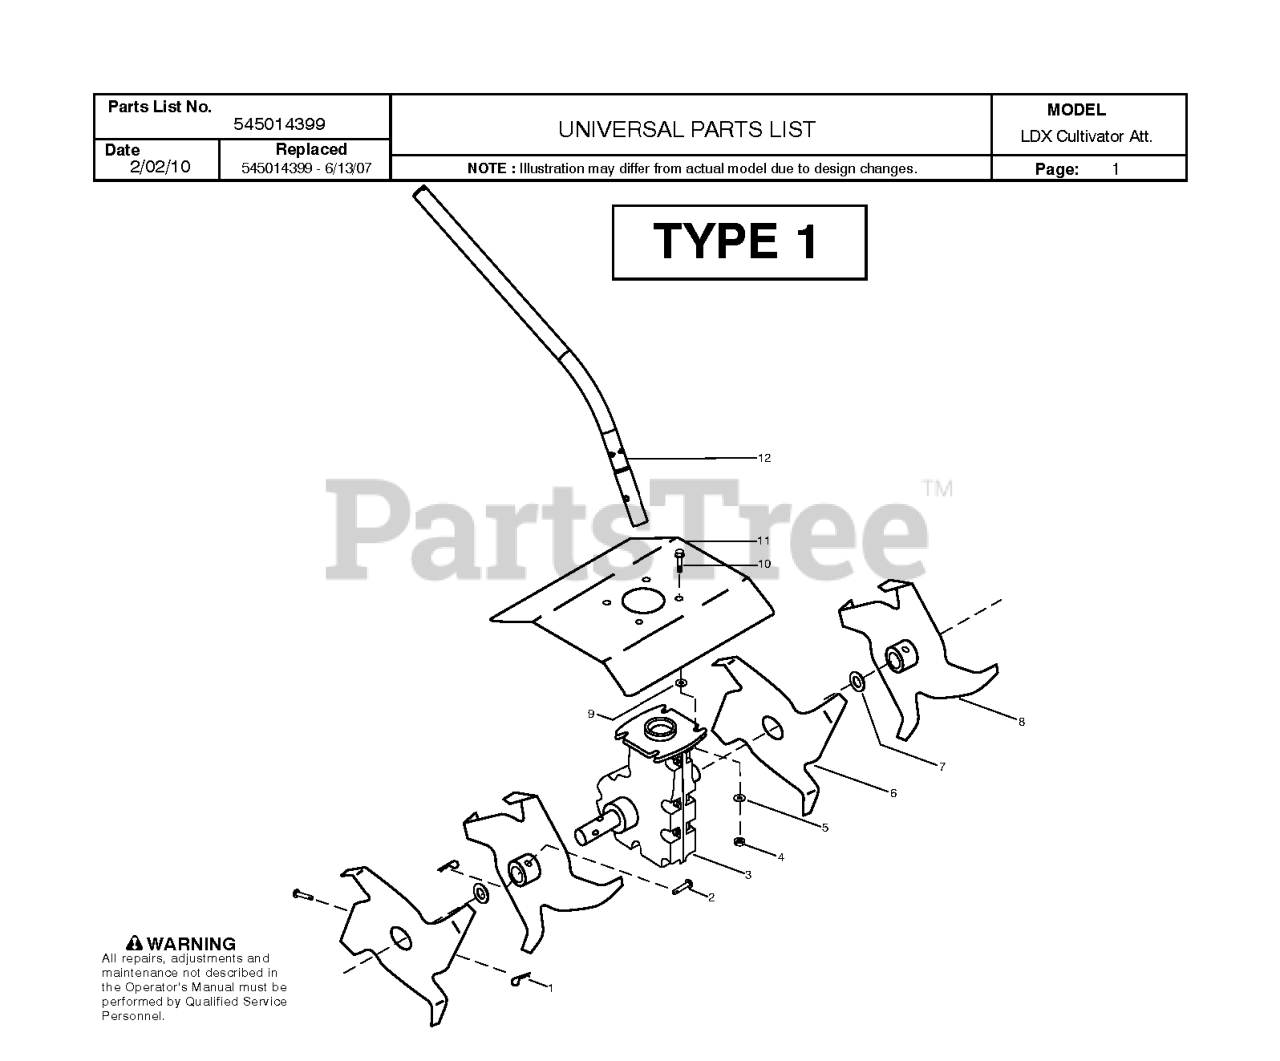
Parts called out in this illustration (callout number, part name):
1	RETAINER,HAIRPIN
2	PIN,CLEVIS
3	GEAR ASSY GEARBOX
5	WASHER,FLAT
6	TINE,RIGHT OUTSIDE/LEFT INSIDE
7	WASHER,FELT
8	TINE,LEFT OUTSIDE/RIGHT INSIDE
9	WASHER,FLAT
10	BOLT,WASHER HEAD
12	SHAFT
